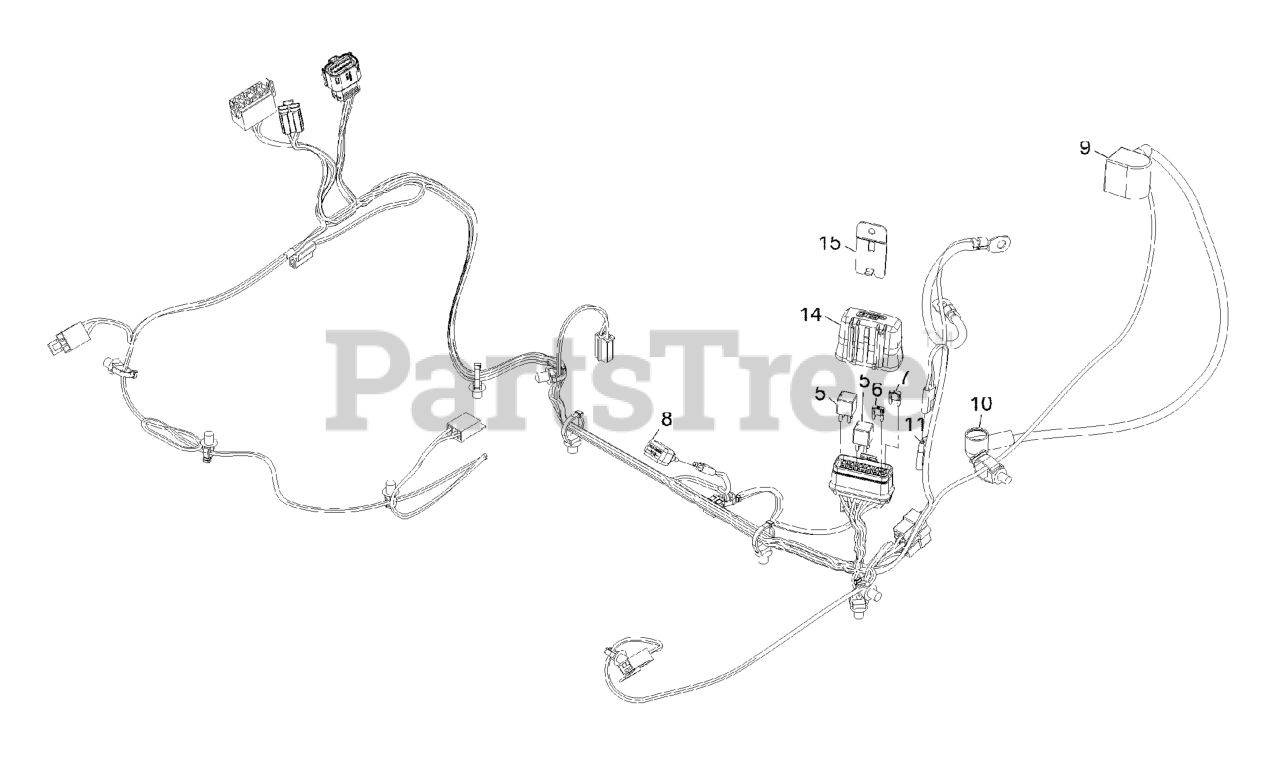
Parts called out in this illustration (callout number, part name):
5	RELAY-MICRO
6	FUSE-MINI BLADE, 15 AMP
7	FUSE-MINI BLADE, 20 AMP
9	INSULATOR-BATTERY
10	INSULATOR-SOLENOID
11	CAP-PLUG
14	COVER-BLOCK, FUSE
15	CLIP-MOUNTING
